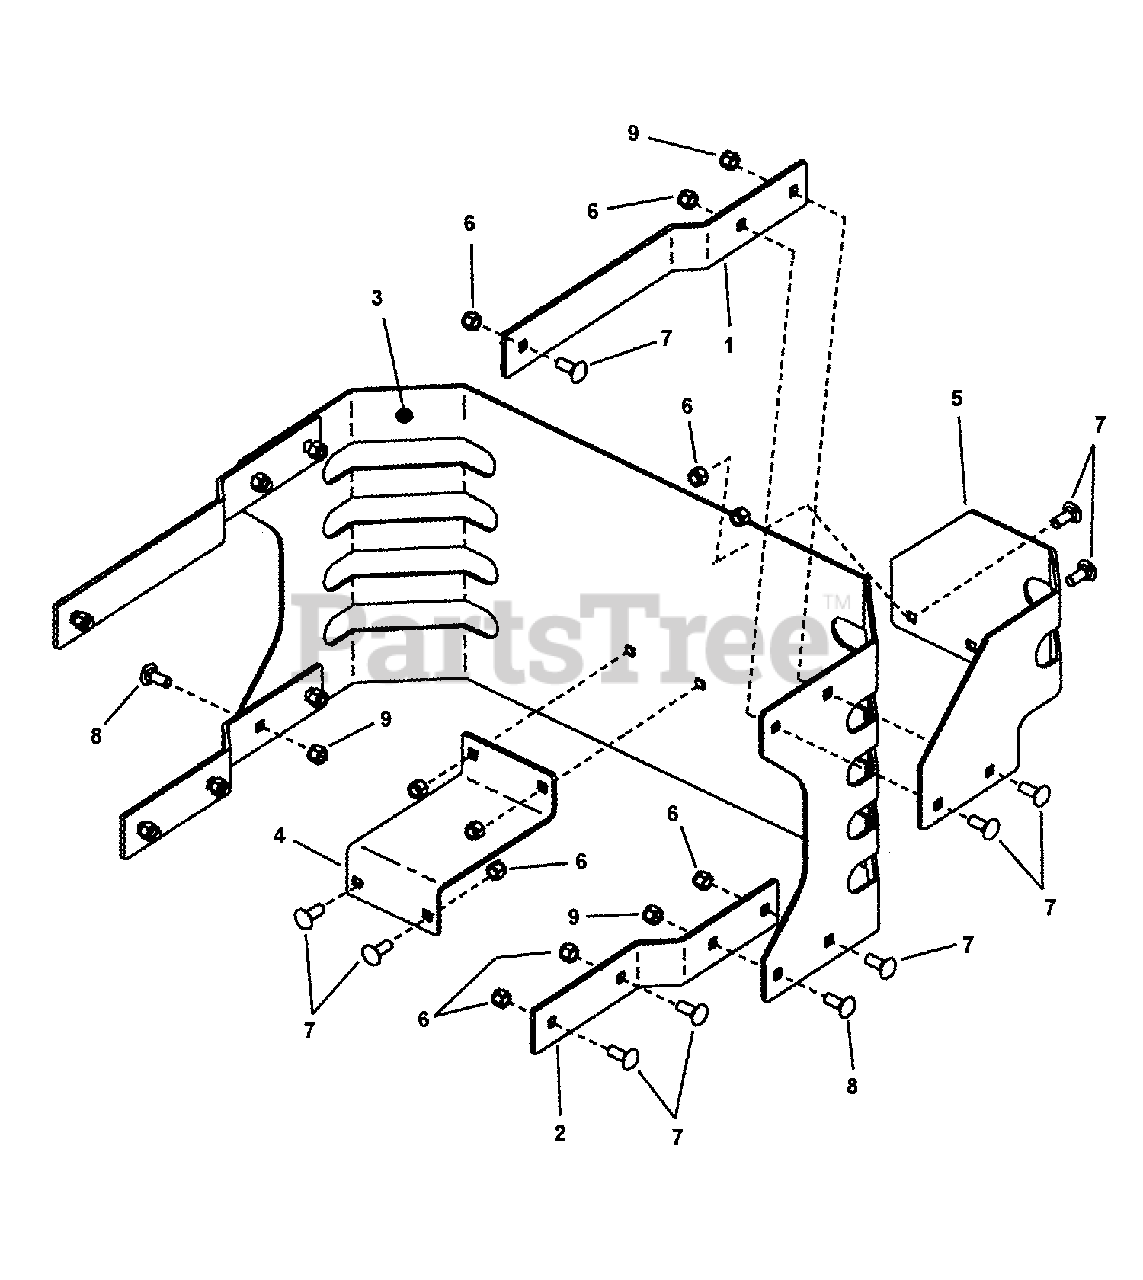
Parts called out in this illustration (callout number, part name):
1	UPPER BRACKET, Muffler Guard
2	MOUNT, Lower Muffler Guard
3	GUARD, Muffler (Back Plate)
4	REAR BRACE, Muffler Guard
5	GUARD, Muffler
6	NUT, 3/8-16 HEX NYLON LOCK
7	BOLT, 3/8-16 x 1" Square Neck Carriage GR 5
8	BOLT, 3/8-16 x 3/4" Square Neck Carriage
9	NUT, 3/8-16 Hex Center Lock
